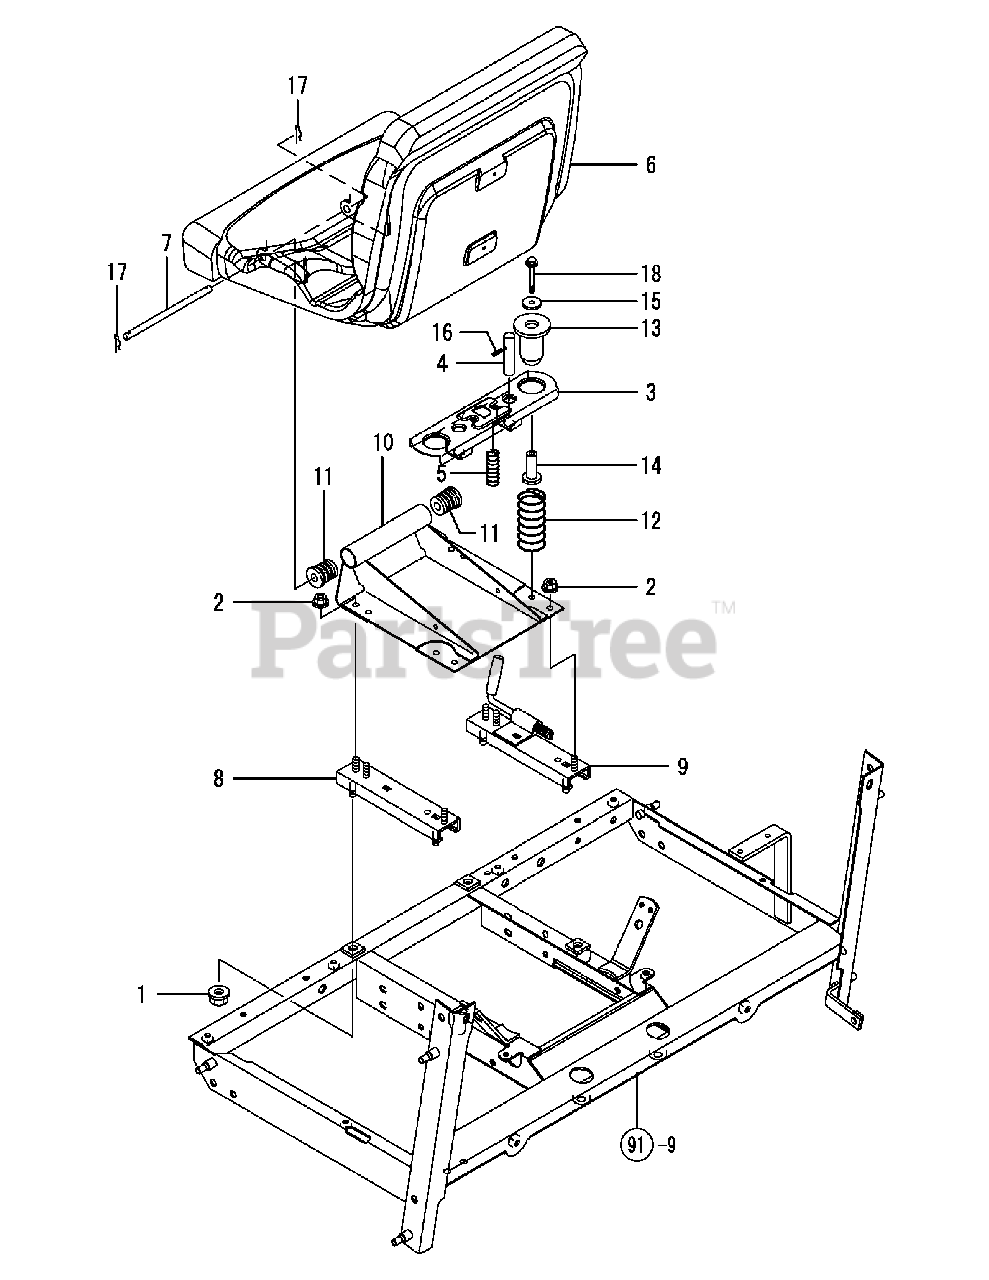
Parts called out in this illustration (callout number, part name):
1	NUT W/WASHER 8
2	NUT W/WASHER 8
3	BRACKET, SEAT SPRING
8	ADJUSTER, BELT
9	ADJUSTER, BELT
10	LOWER BRACKET,SEAT
12	SPRING, CUSHION
13	RUBBER, CUSHION
15	WASHER 8.5X22X2.3
16	SPRING PIN 3X25
18	BOLT M 8X 70 PLATED
